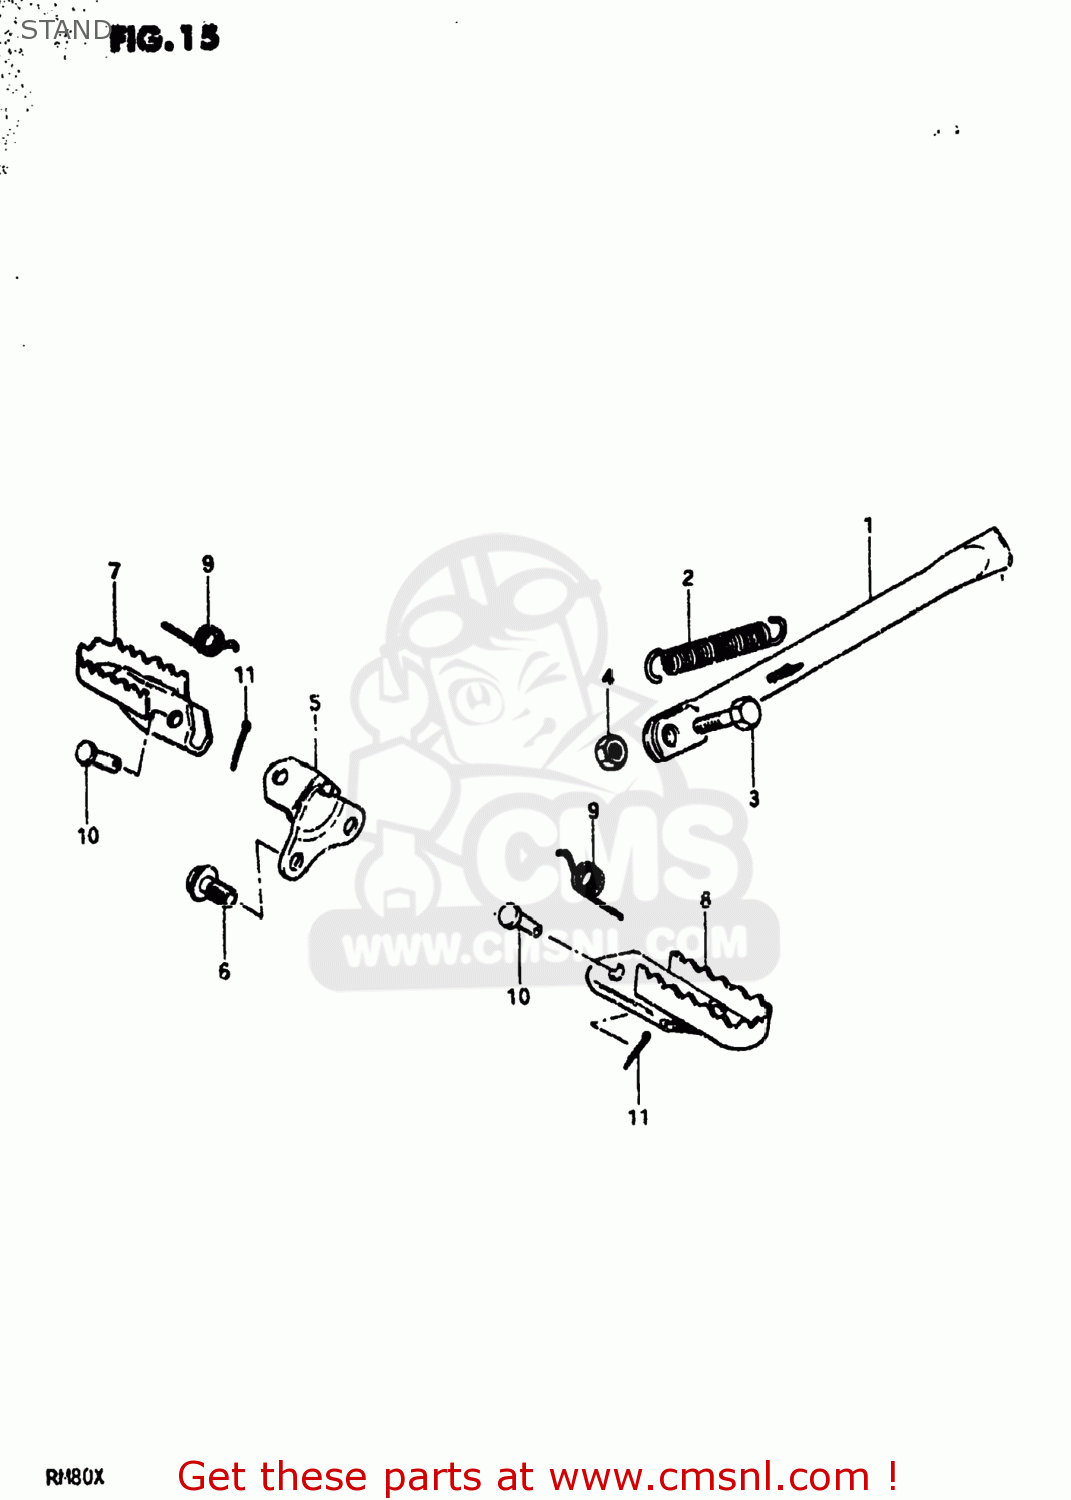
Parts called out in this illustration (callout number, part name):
1	STAND,SIDE
2	SPRING
3	BOLT
4	NUT
5	BAR,FRONT FOOTREST
6	BOLT(10X20)
7	FOOTREST,FRONT,RIGHT
8	FOOTREST
9	SPRING
10	PIN
11	PIN 20X20
